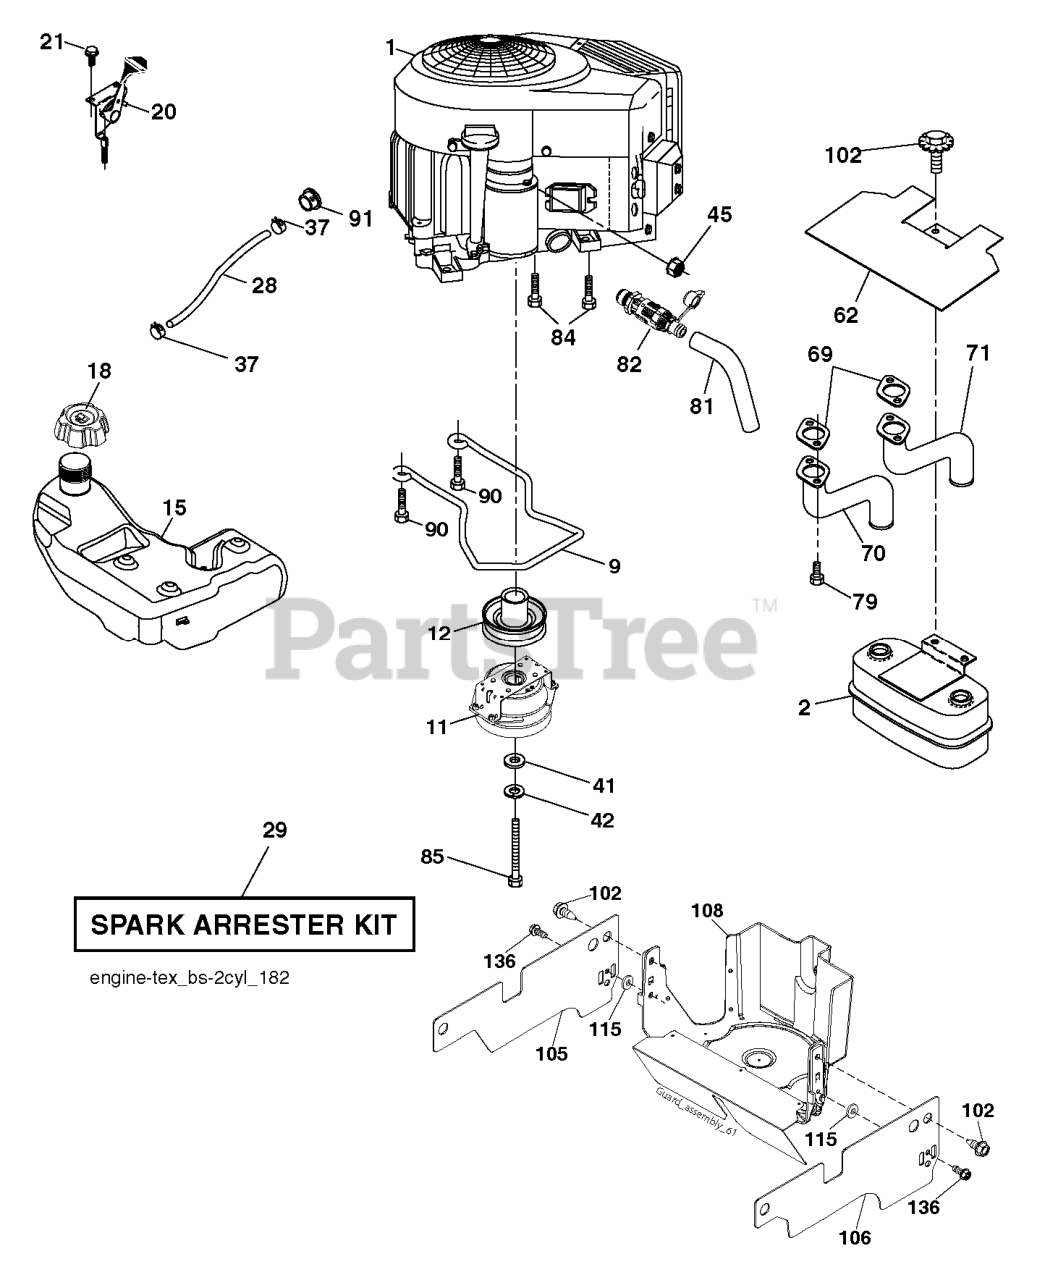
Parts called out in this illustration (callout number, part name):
2	MUFFLER.ASM.TWIN.MNTG.BRACKET
9	KEEPER.BELT.ENG.4.25"2.BLT.431
11	CLUTCH.OGURA.4.4PD.GT1.5-EH13V
12	PULLEY.ENGINE.TUFFTORQ
15	FUEL.TANK.ASM.3.0GAL.REAR.2019
18	CAP ASSY FUEL 3" GRAY
18	FUEL CAP
20	THROTTLE.COBRA.38"READSTART.BK
21	SCREW.#10 X 0.750.BOS
28	REPL BY 532 00 85-43
29	KIT.SPARK ARRESTOR 794945 B&S
37	HOSE CLAMP
42	WASHER 7/16 LOCK
45	NUT
62	SHIELD.HEAT.MUFFLER
69	GASKET.MUFFLER
70	EXHAUST.TUBE.LH.BS/TWIN
71	EXHAUST.TUBE.RH.B&S.TWIN.INTEK
79	SCREW.SOCKET.HEAD.5/16-18
81	TUBE, DRAIN OIL ASM.
82	VALUE.OIL.DRAIN
84	SCREW.3/8-16
85	CLUTCH BOLT7/16-20X3.5 GR524HR
90	SCREW 3/8-16X1
91	BUSHING.1.375OD
102	SCREW
105	SHIELD.SIDE.LH.3842"TEX FRN.BK
106	SHIELD.SIDE.LH.3842"TEX FRN.BK
108	COVER.PULLEY.ENG.W/SHLD.38"42"
136	SCREW.#10 X 0.500
